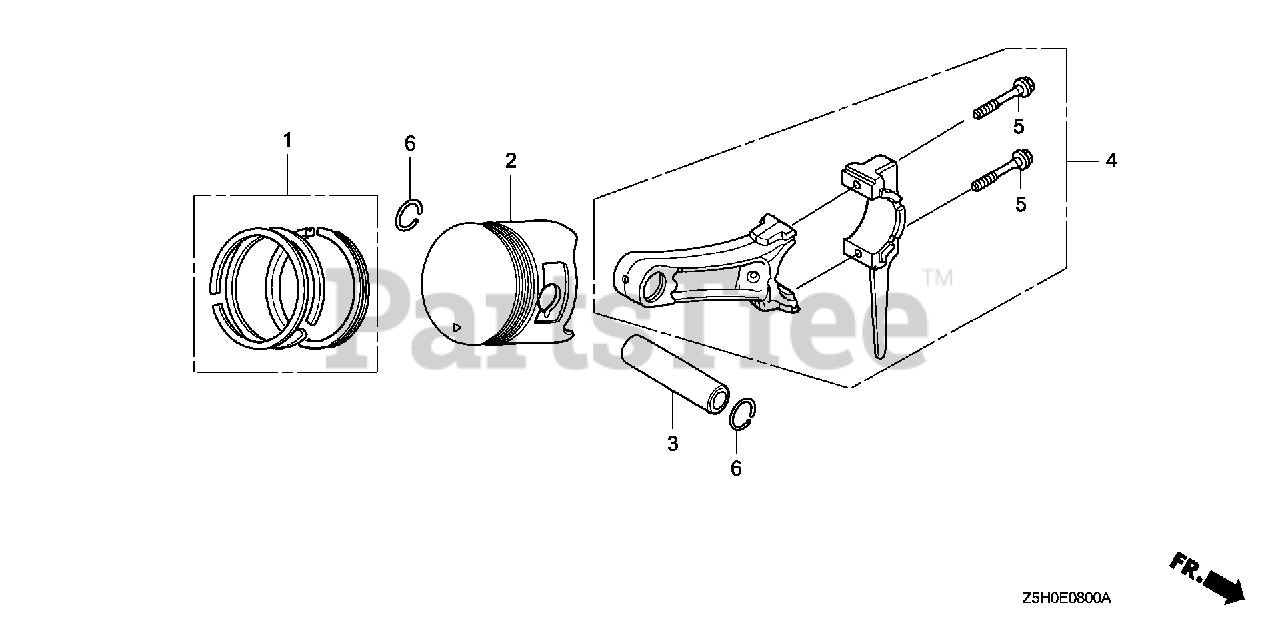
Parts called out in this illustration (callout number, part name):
1	RING SET, PISTON (STD) (NIPPON)
1	RING SET, PISTON (STD.) (TEIKOKU)
1	RING SET, PISTON (OS 0.25)
1	RING SET, PISTON (0.25) (TEIKOKU)
1	RING SET, PISTON (OS 0.50)
1	RING SET, PISTON (0.50) (TEIKOKU)
1	RING SET, PISTON (0.75) (NIPPON)
1	RING SET, PISTON (0.75) (TEIKOKU)
2	PISTON (STD)
2	PISTON (OS 0.25)
2	PISTON (0.25)
2	PISTON (OS 0.50)
2	PISTON (0.50)
2	PISTON (0.75)
3	PIN, PISTON
4	ROD ASSY., CONNECTING (STD)
4	ROD ASSY., CONNECTING (Honda Code 2110153). (US 0.25)
5	BOLT, CONNECTING ROD
6	CLIP, PISTON PIN (18MM)
